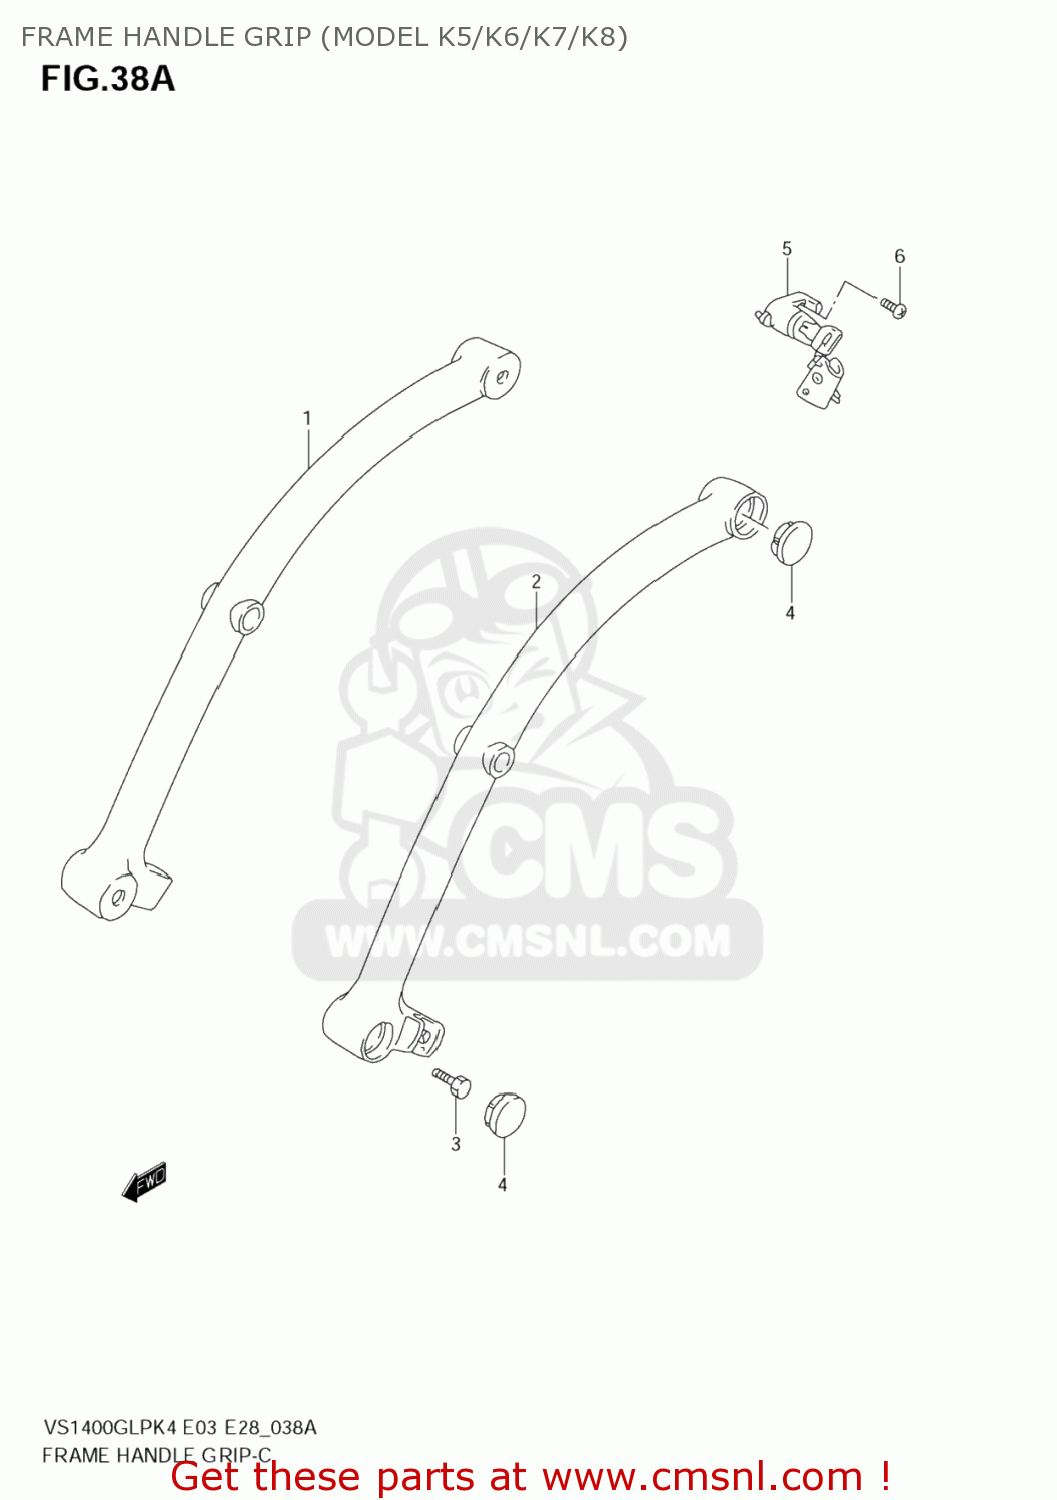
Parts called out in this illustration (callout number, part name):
1	GRIP,FRAME HANDLE,R
2	GRIP,FRAME HANDLE,L
3	BOLT
4	CAP,PIPE CO-RIDER GRIP
5	LOCK SET,HELMET
6	SCREW
